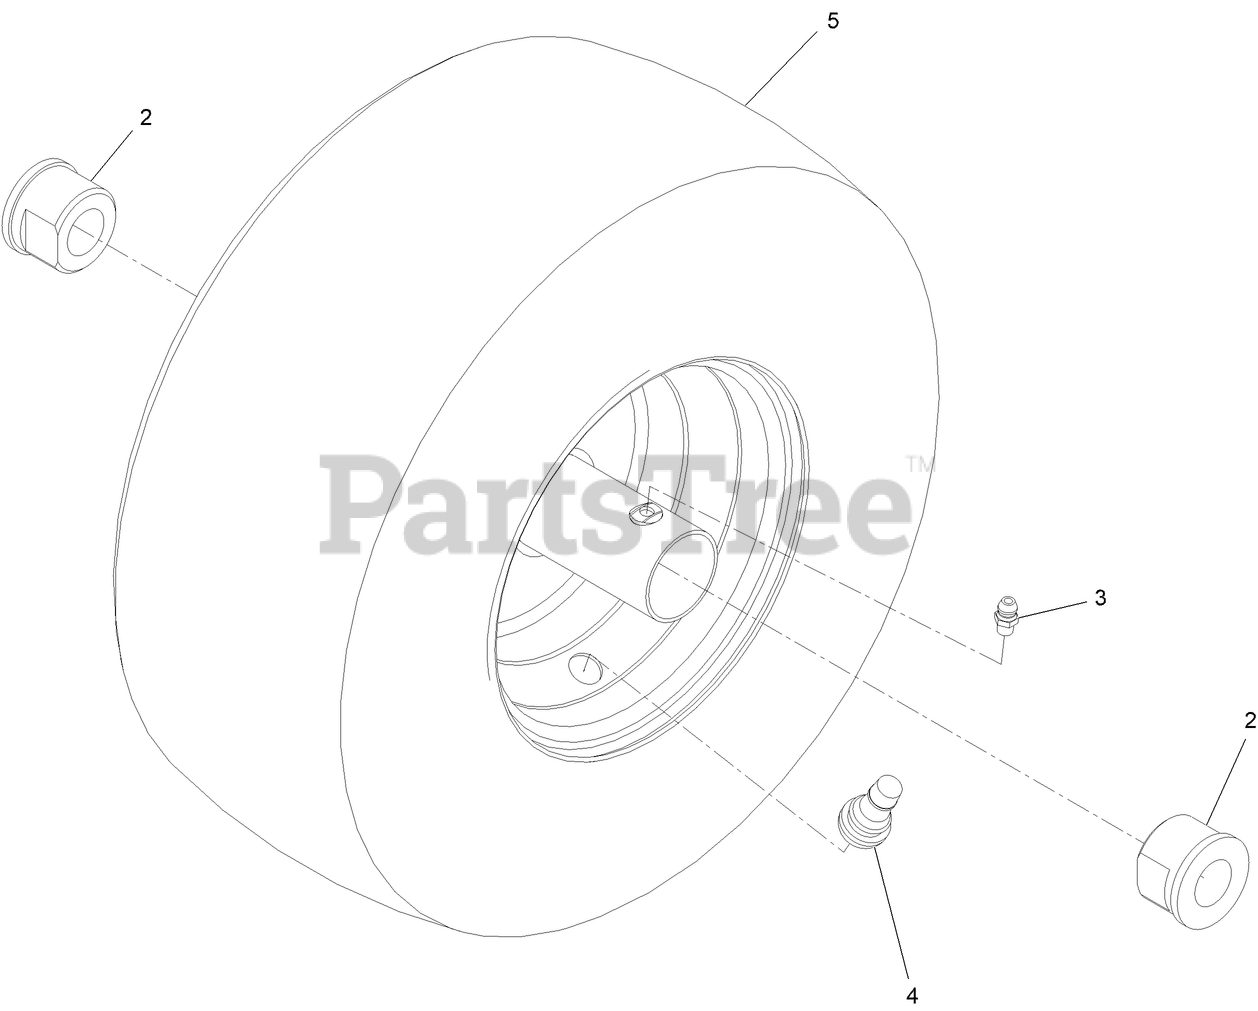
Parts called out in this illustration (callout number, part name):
2	BUSHING-FLANGE
3	FITTING-GREASE
4	VALVE
